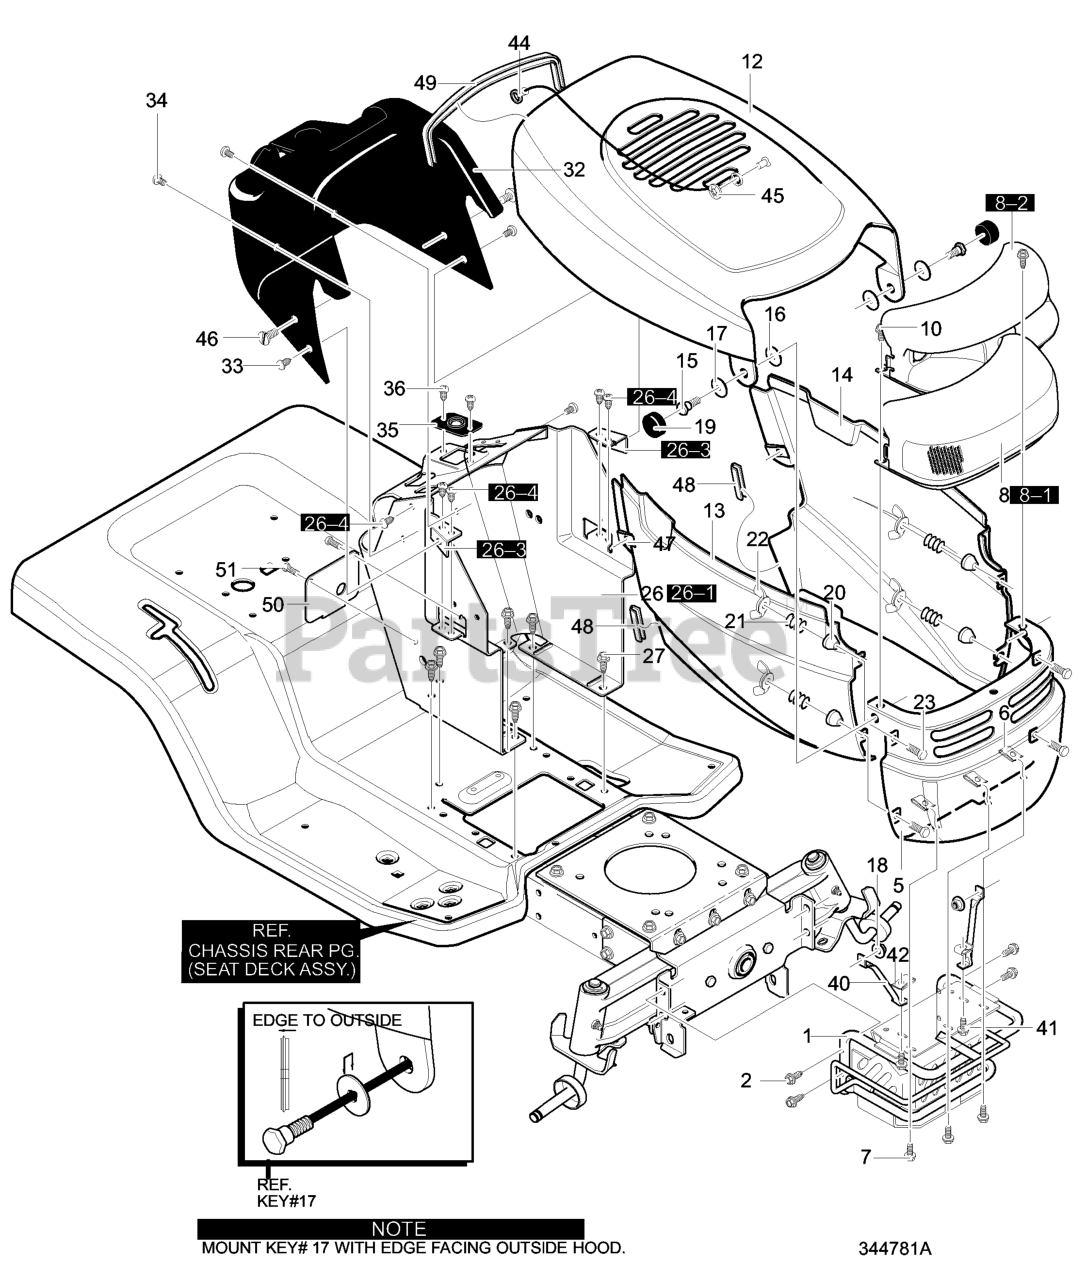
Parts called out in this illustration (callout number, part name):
1	ASSEMBLY, BUMP/GRILLE
2	SCRW5/16-18X1.50
6	NUT, "J" TINNERMAN
7	SCRW,1/4-20X .63
8	ASM., LENS & REFLECTOR
8-2	REFLECTOR
10	SCREW 1/4-14X.50
12	ASM., WELD HOOD H26
13	PANEL, SIDE RH
14	PANEL, SIDE LH
16	WASHER, PLASTIC BLACK
17	PIVOT BASE GREY
18	NUT, 3/8-16
19	PIVOT CAP GREY
20	QUICK RELEASE-CAM
21	SPRING, COMP
22	NUT, WING 1/4-20
23	SCREW, 1/4-20X1.25
26	ASM., CONSOLE
26-1	CONSOLE
26-2	BRACKET, LEFT
26-3	BRACKET, RIGHT
27	SCRW 5/16-18X.75
32	DASH, H26 GREY
33	SCREW, 10-24X.50
34	SCREW, 10-24X.50
35	STEERING BRACKET
36	SCREW 1/4-14X.50
40	STRUT, H26 GRILLE
41	SCREW, 1/4-20X .63
42	SPEED NUT
44	LANYARD, H26 HOOD
45	PUSHNUT
46	SCREW, 1/4-20X0.63
47	NUT, "J" TINNERMAN
48	TRIM PIECE PLASTIC GREY
49	TRIM PIECE PLASTIC GREY
50	ACCESS PANEL, W/O SLOT
51	SCREW, 10-24X.50
